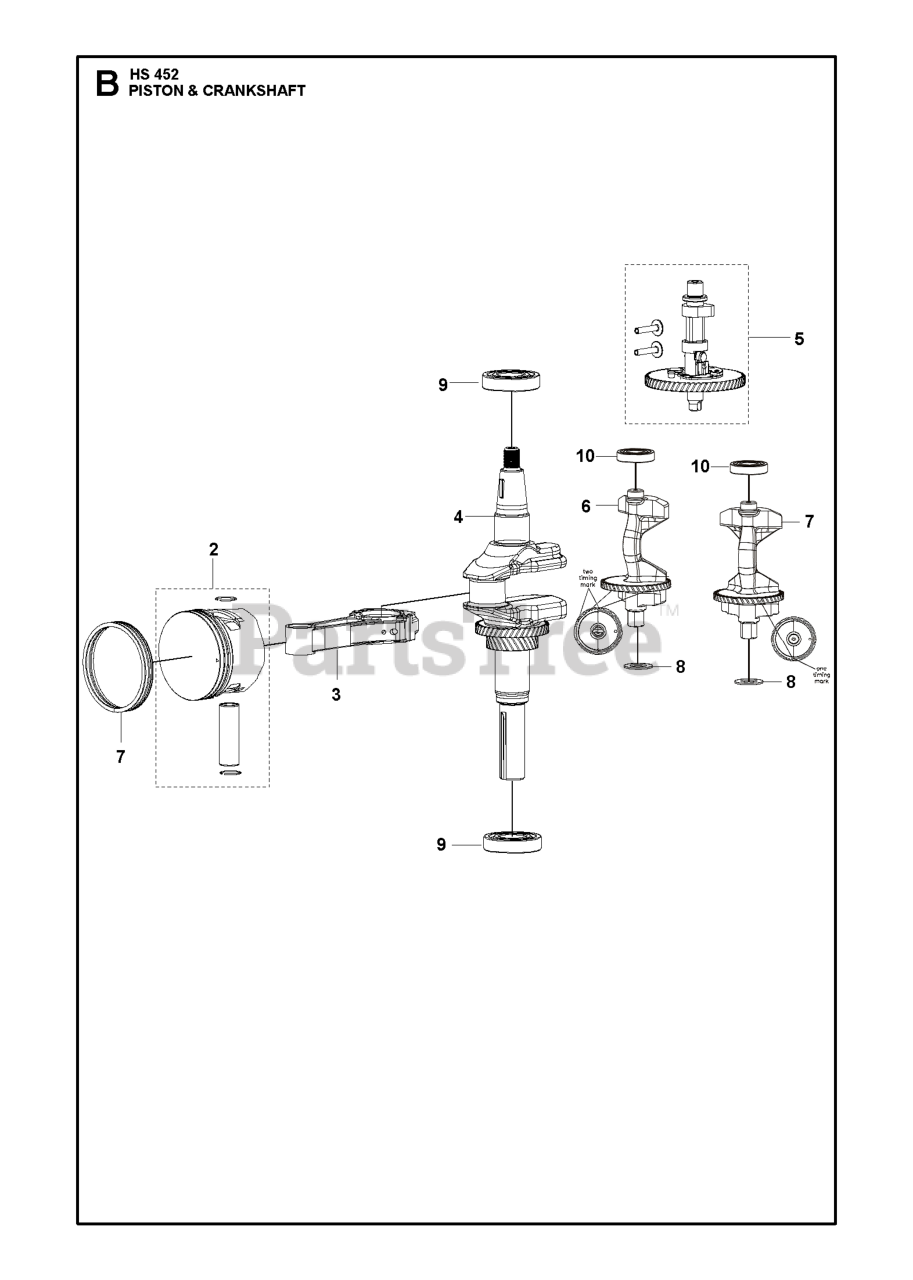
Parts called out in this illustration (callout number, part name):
1	PISTON RING SET
2	PISTON ASSY
3	CONNECTING ROD
4	CRANKSHAFT
5	CAMSHAFT KIT
6	SHAFT BALANCING SHAFT
7	SHAFT BALANCING SHAFT.
8	WASHER T370: 17.4 X 30 X 1.5
9	BALL BEARING BALL BEARING
10	BALL BEARING BALL BEARING
